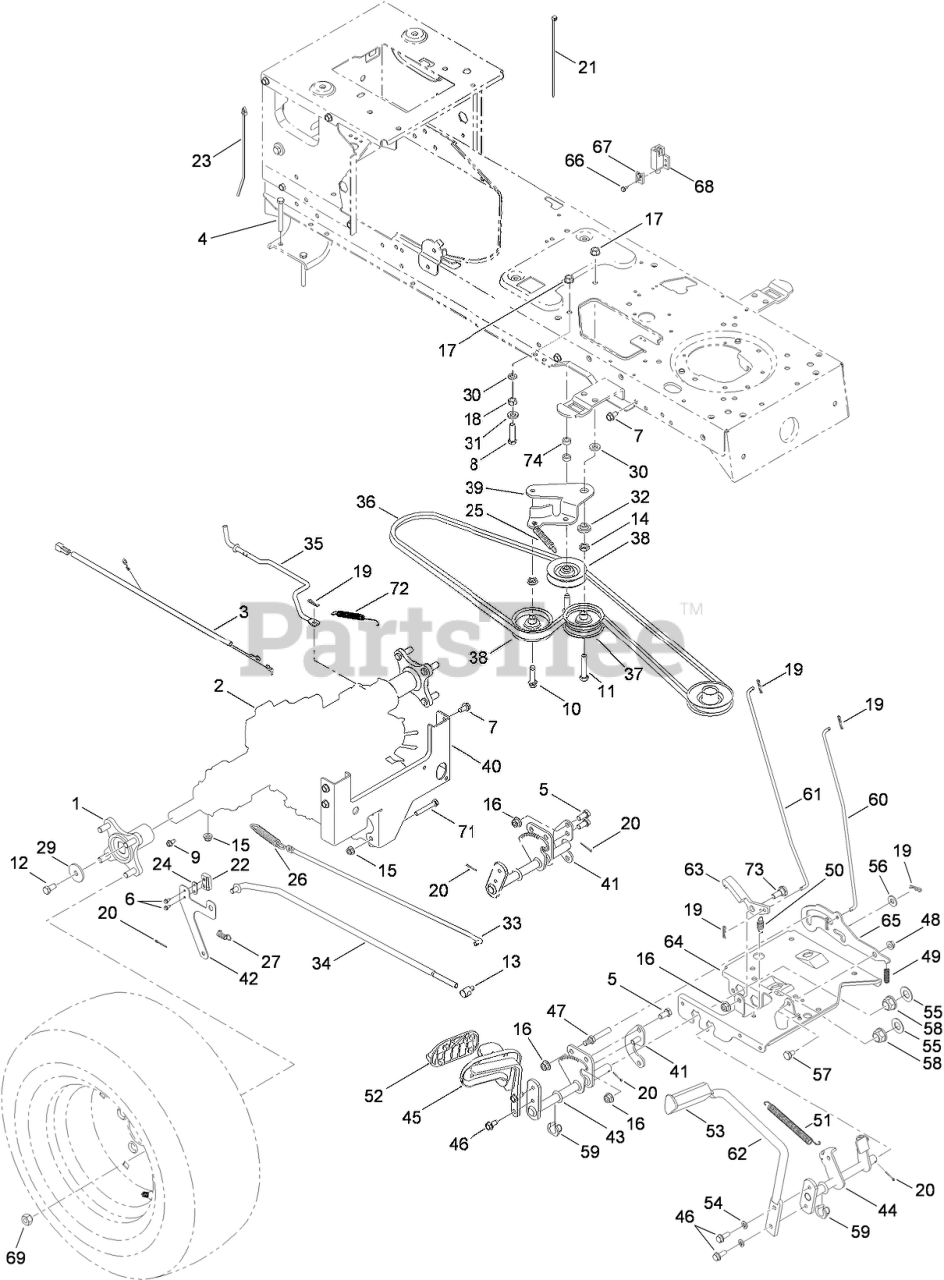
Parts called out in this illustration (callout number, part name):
1	WHEEL HUB ASM
2	HYDROSTATIC TRANSMISSION ASM
3	HARNESS ASM
4	SCREW-HH
5	SCREW-HH
6	SCREW-HWHTF
7	SCREW-TAP
8	SCREW-HH
9	SCREW-HWHTF
10	SCREW-TAP
11	SCREW-HH
12	SCREW-HH
13	FERRULE
14	NUT-JAM
15	NUT-LOCK, FLANGE
16	NUT-LOCK, FLANGE
17	NUT-LOCK, FLANGE
18	NUT-LOCK, FLANGE
19	PIN-COTTER
20	PIN-COTTER
21	TIE-CABLE
22	SWITCH-SPRING, SHORT
23	TIE-CABLE
24	PLATE-INSULATOR
25	SPRING-EXTENSION
26	SPRING-EXTENSION
27	SPRING-EXTENSION
29	WASHER-FLAT
30	WASHER-FLAT
31	WASHER-FLAT
32	SPACER-SHOULDER
33	ROD-BRAKE, HYDROSTATIC
34	ROD-CONTROL, HYDROSTATIC
35	ROD-BYPASS, HYDROSTATIC
36	BELT-V, TYPE
37	PULLEY-IDLER, FLAT
38	PULLEY-IDLER, Y TYPE
39	BRACKET-IDLER, CENTER DOUBLE
40	BRACKET-TORQUE, TRANSMISSION
41	BRACKET-CONTROL
42	BRACKET-ACTUATOR, SWITCH
43	CONTROL ASM
44	SPEED CONTROL ASM
45	CONTROL PEDAL ASM
46	SCREW-HWH
48	NUT-LOCK, FLANGE
49	SPRING
50	SPRING-EXTENSION
51	SPRING-EXTENSION
52	PAD-PEDAL
53	PAD-BRAKE
54	WASHER-LOCK
55	WASHER-FLAT
56	Washer-Flat
57	BOLT-SHOULDER
58	BEARING-FLANGE
59	BEARING-FLANGE, HEX (SPLIT)
60	ROD-BRAKE, LOCK
61	ROD-CONTROL, CRUISE
62	PEDAL-BRAKE
63	LATCH-CRUISE
64	BRACKET-SUPPORT, STEERING
65	BRACKET-LOCKOUT
66	SCREW-TAP
67	PLATE-SWITCH
68	SWITCH-INTERLOCK
69	NUT-LUG
71	SCREW-HH
72	SPRING-EXTENSION
73	BOLT-SHOULDER
74	SPACER
